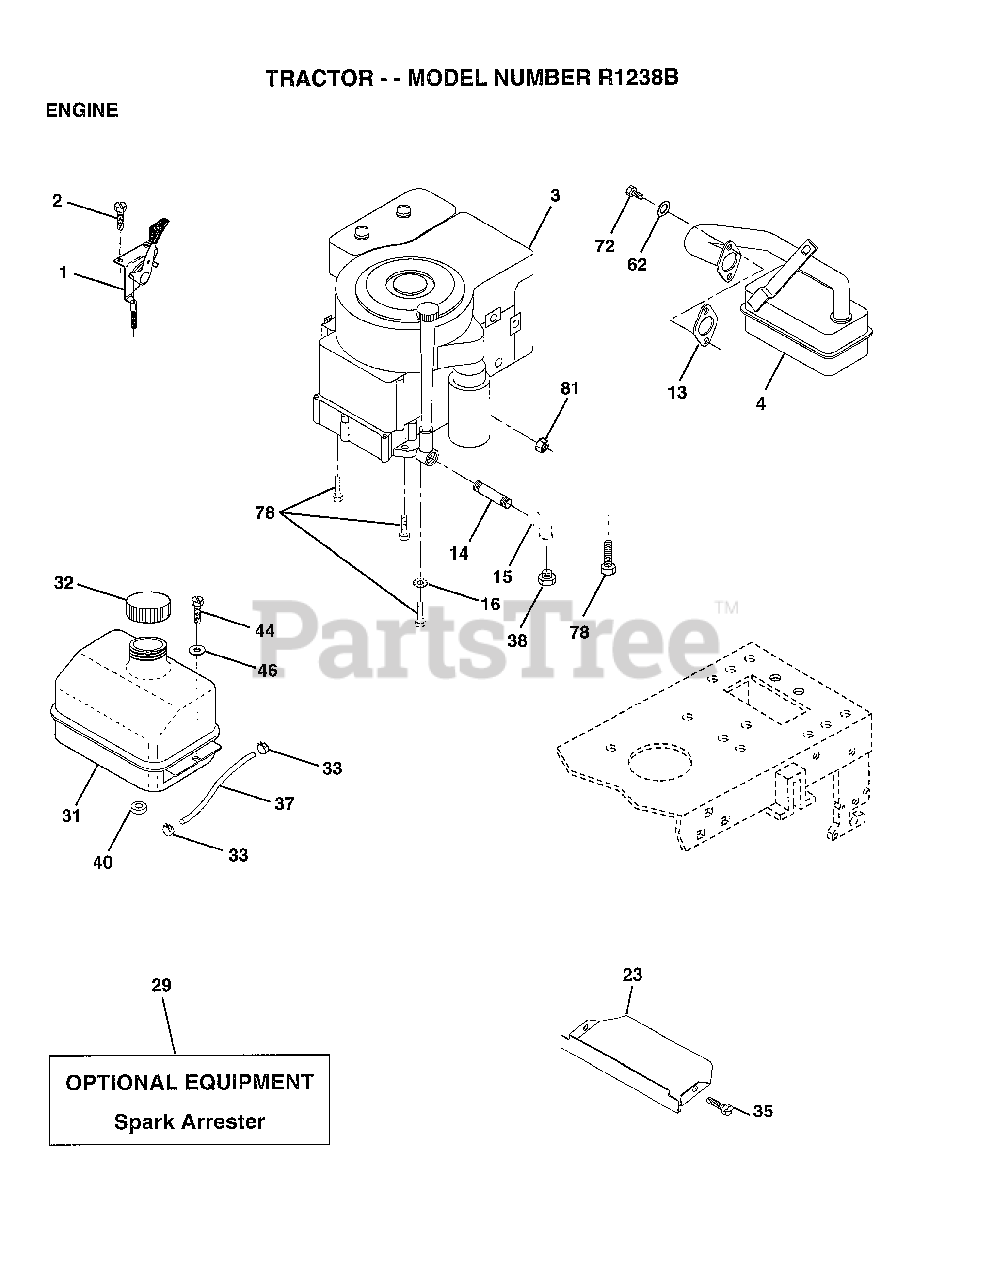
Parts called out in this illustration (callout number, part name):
1	THROTTLE CONTROL
2	SCREW LT
4	MUFFLER
13	GASKET ENG 1 313 LD TIN PLATED
14	PIPE NIPPLE
15	ELBOW
16	LOCKWASHER
23	SHIELD.BRN/DBR.GD
31	TANK.FUEL.LT.
32	CAP ASM FUEL
33	HOSE CLAMP
35	SCREW
37	LINE FUEL
44	SCREW HEX CRT
46	WASHER
62	LOCKWASHER
72	SCREW
78	SCREW
81	NUT
